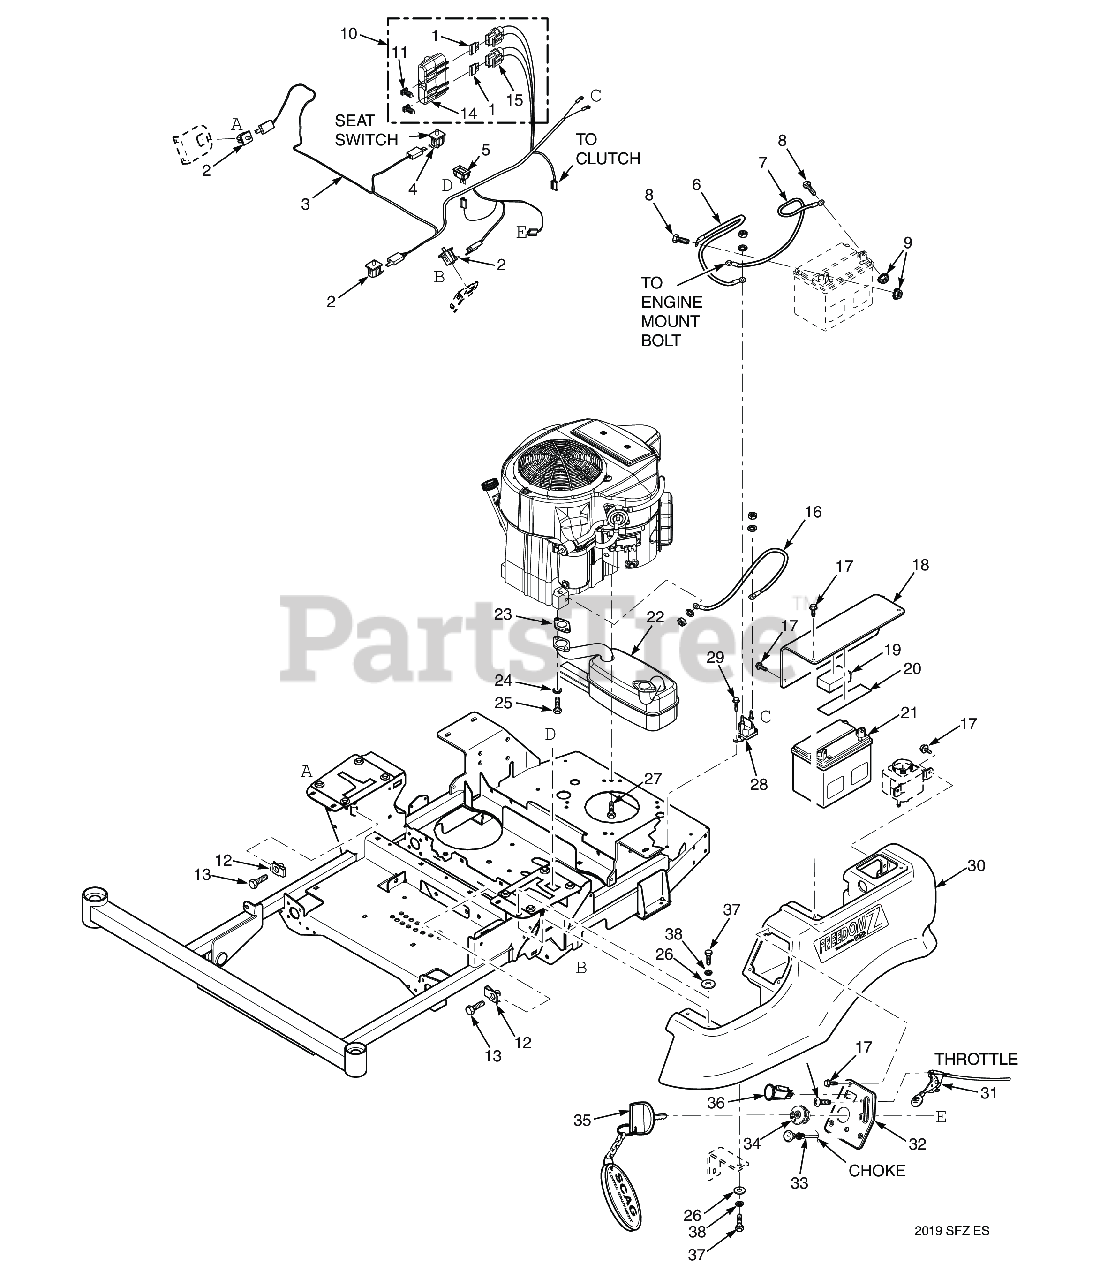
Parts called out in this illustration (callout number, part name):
1	FUSE, 20 AMP BLADE TYPE AUTOMOTIVE
2	Switch, Double Pole - Plunger
3	Wire Harness, Main
4	Switch, Double Pole - Plunger
5	Hourmeter
6	Battery Cable, 25" Red (Kawasaki)
7	Battery Cable, 27" Black (35BV & 37BV-EFI) - Briggs & Stratton
8	Bolt, Hex Head 1/4-20 x .5" Battery, (Not Available Through Scag)
9	Nut, 1/4 - 20 Hex
10	Double Fuse Assy.
11	Clip, Fuse Holder
12	U-Nut, 3/8-16 (short)
13	Bolt, Hex Head 3/8-16 x 1-1/4" with Thread Lock Patch
14	Cover, Sealed Double
15	Fuse Holder Assembly
16	Battery Cable, Red 9" (Briggs & Stratton)
17	CAP SCREW, 1/4-20 X 1/2" SERRATED FLANGE HEX
18	Battery Cover
19	Pad, Battery Hold Down
20	Rubber Pad
21	Battery, 350 CCA (not available through Scag)
22	Muffler, Kohler KT
23	Muffler, Kohler KT
24	Flatwasher, 5/16-.375 x .875 x .083 (35BV & 37BV-EFI)
25	Bolt, Hex Head 3/8-16 x 1-1/4", Kawasaki FX / FS
26	Lockwasher, 3/8" Spring, Kawasaki FX / FS
27	Bolt, Hex Head Self-Tap 3/8-16 x 1-1/4" (Kohler x3 - 25EFI, Kohler x4 - 29EFI)
28	Solenoid, Sealed (Briggs & Stratton)
29	Screw, Self-Tapping 1/4-20 x 3/4
30	Tank Console 48
30	Tank, LH - SPZ
31	Throttle Control, Kawasaki
32	INSTR PANEL W/ DECAL, SFZ
33	Choke Control, Kawasaki
34	Ignition Switch
35	Key, Assembly w/Fob
36	Switch, PTO - 10 Amp
37	BOLT, SERRATED FLANGE HEX HEAD 5/16-18 X 3/4"
38	Lockwasher, 5/16 (.317 x .586 x .078) Helical Spring
